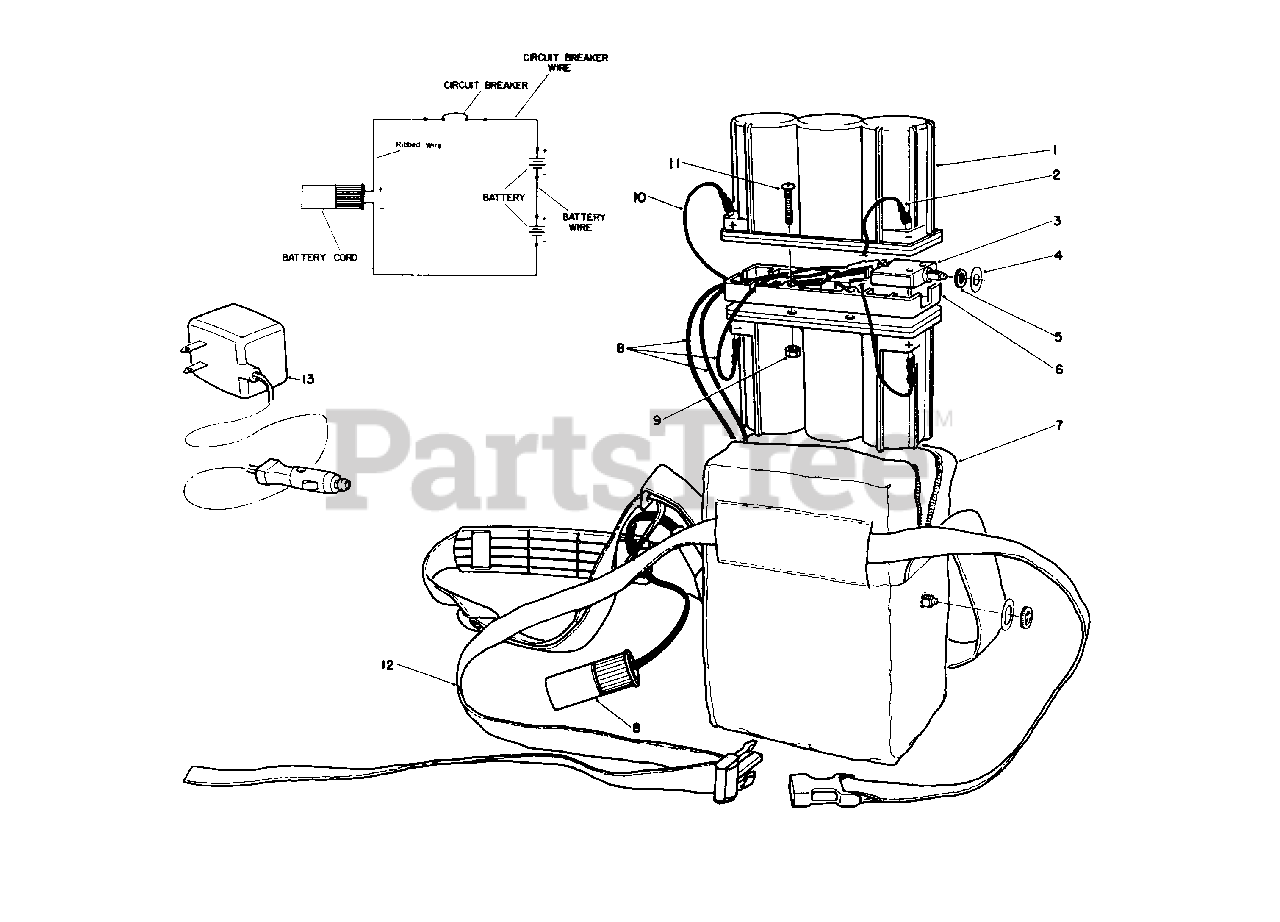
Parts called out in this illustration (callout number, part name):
1	Battery-6 Volt
2	Wire-Battery
3	Circuit Breaker
4	Plate-Breaker, Circuit
5	Nut-Knurled
6	Spacer-Battery
7	Pack-Soft
8	Cord-Battery
10	Wire-Breaker, Circuit
11	Screw-Phillips, Pan Hd.
13	Charger 12 Volt
